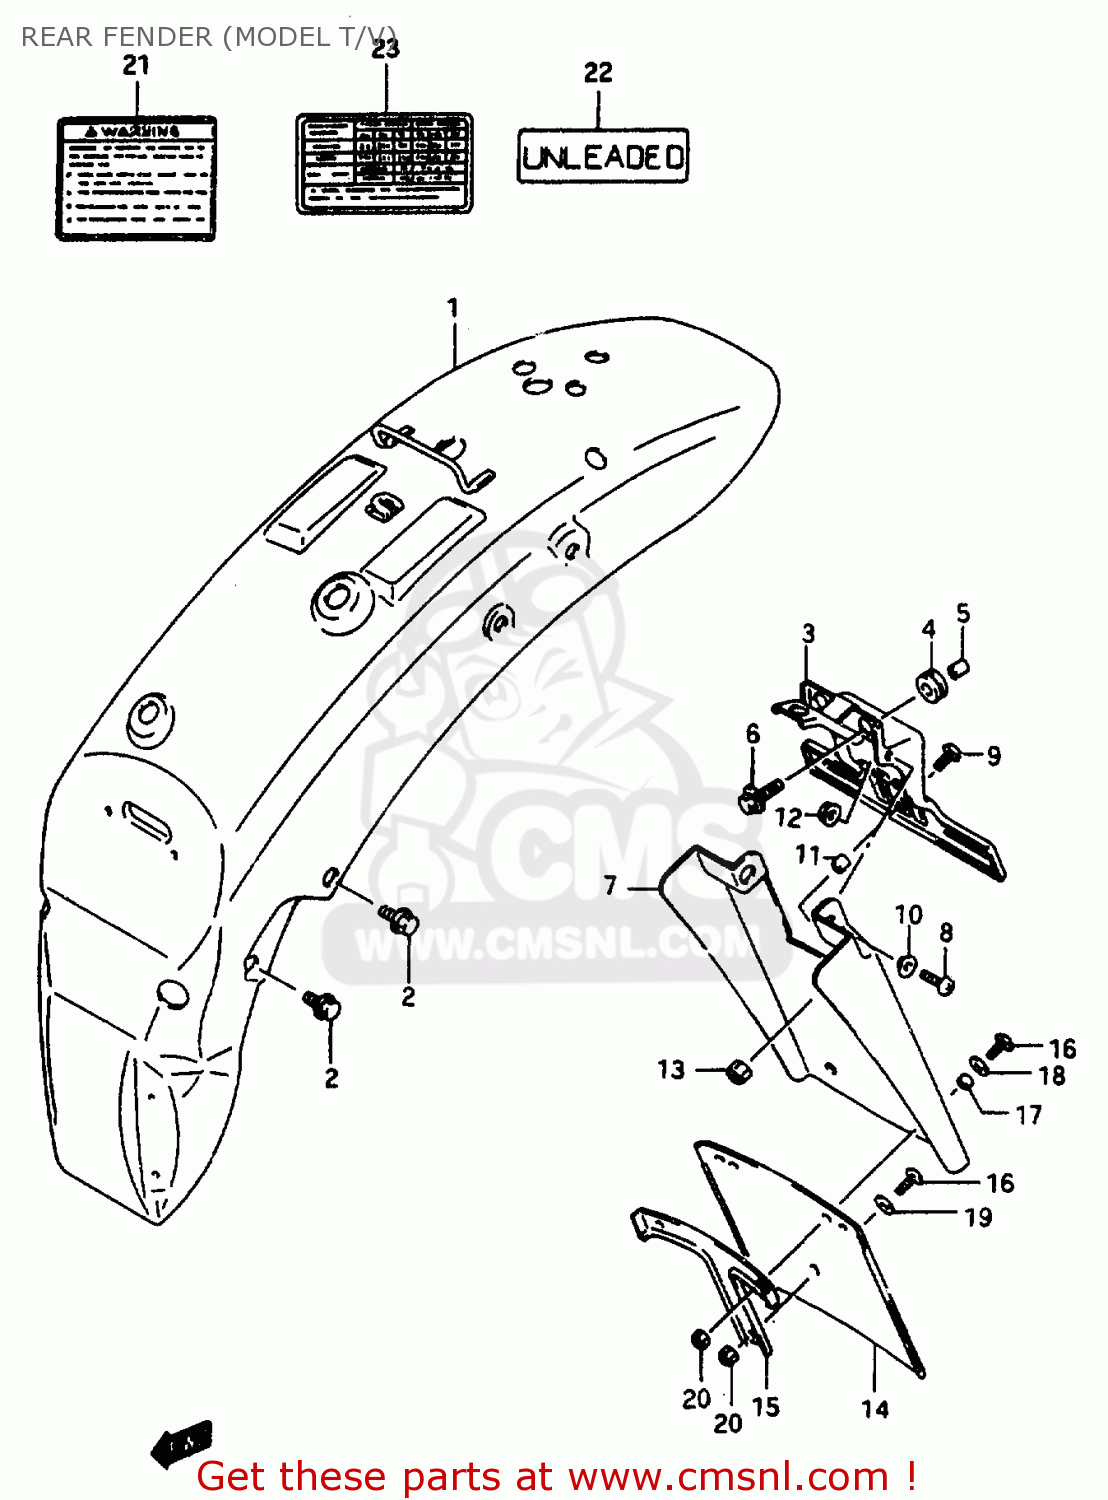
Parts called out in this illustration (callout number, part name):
1	FENDER,RR
2	BOLT
3	BRACKET,LICENSE LAMP
4	CUSHION
5	SPACER
6	BOLT(6X20)
7	EXTENSION,RR FENDER
8	SCREW
9	SCREW 6X16
10	WASHER
11	SPACER(6.2X8.3X6.1)
12	NUT
13	NUT
14	MUD FLAP, REAR FENDER
15	PLATE, MUD FLAP
16	SCREW 5X12
17	SPACER(5.5X8X4)
18	WASHER
19	WASHER(5.5X16X1.2)
20	NUT 8MM
21	LABEL,WARNING
22	LABEL,CAUTION
23	LABEL, AIR PRESSURE
24	VS600/800GL O.
